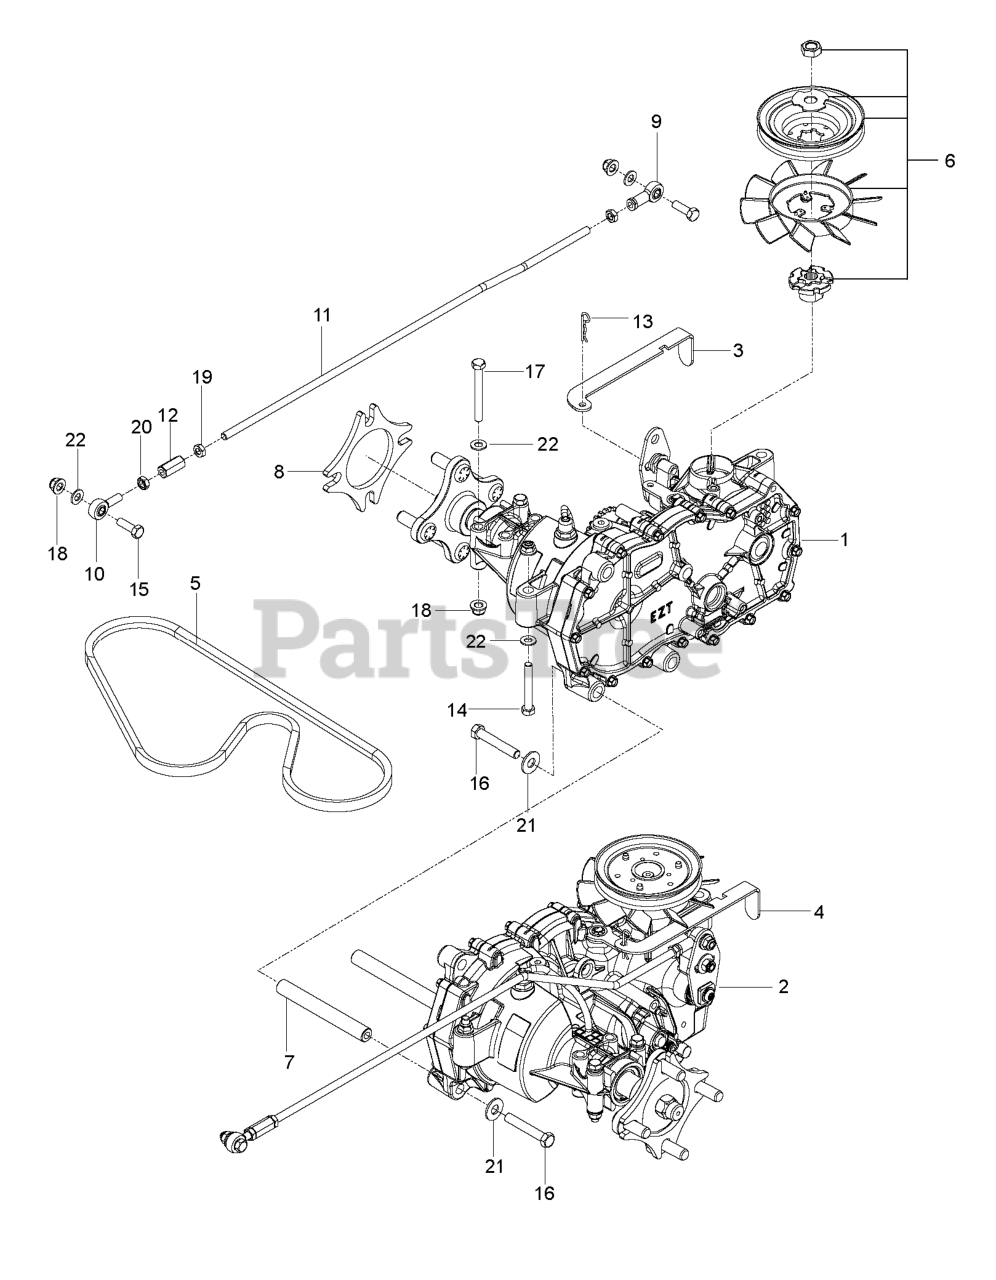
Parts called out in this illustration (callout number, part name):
1	HG_HYDRO RH
2	HG_HYDRO LH
3	RELEASE LEVER RH
4	RELEASE LEVER LH
5	BELT 30 ZEZT
6	KIT FAN/PULLEY 72137
7	HYDRO SPACER
8	SPACER, WHEEL
9	RH ROD END
10	RP.ROD.END.LH
11	CONTROL ROD
12	ROD END COUPLER
13	HAIRPIN #2
14	BOLT.FIN HEX 5/16-18UNC X2 1/4
15	BOLT.FIN.HEX.5/16-18UNC X 1.00
16	BOLT.HEX
18	5/16-18 NYLOC FLANGE NUT
19	NUT 5/16-24 UNF HEX JAM
20	NUT 5/16F LEFTHAND
21	RP WASHER 3/8 FLAT
22	WASHER
